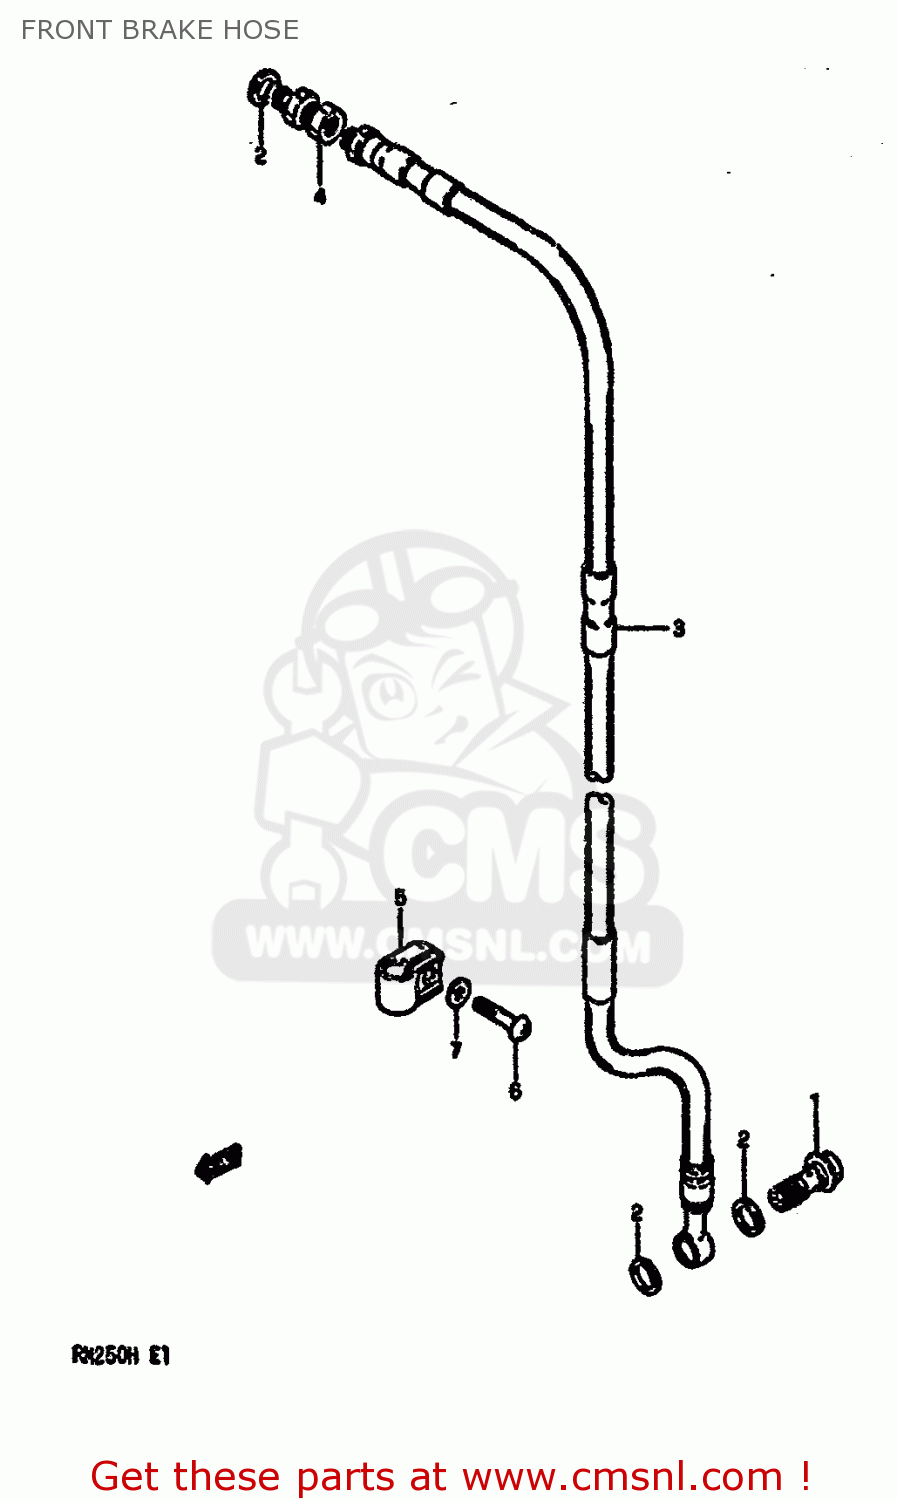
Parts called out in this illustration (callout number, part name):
1	BOLT UNION
2	WASHER(10X15X1.5)
3	HOSE,FRONT BRAKE
4	ADAPTER,BRAKE HOSE
5	CLAMP,FRONT BRAKE HOSE
6	SCREW
7	WASHER
